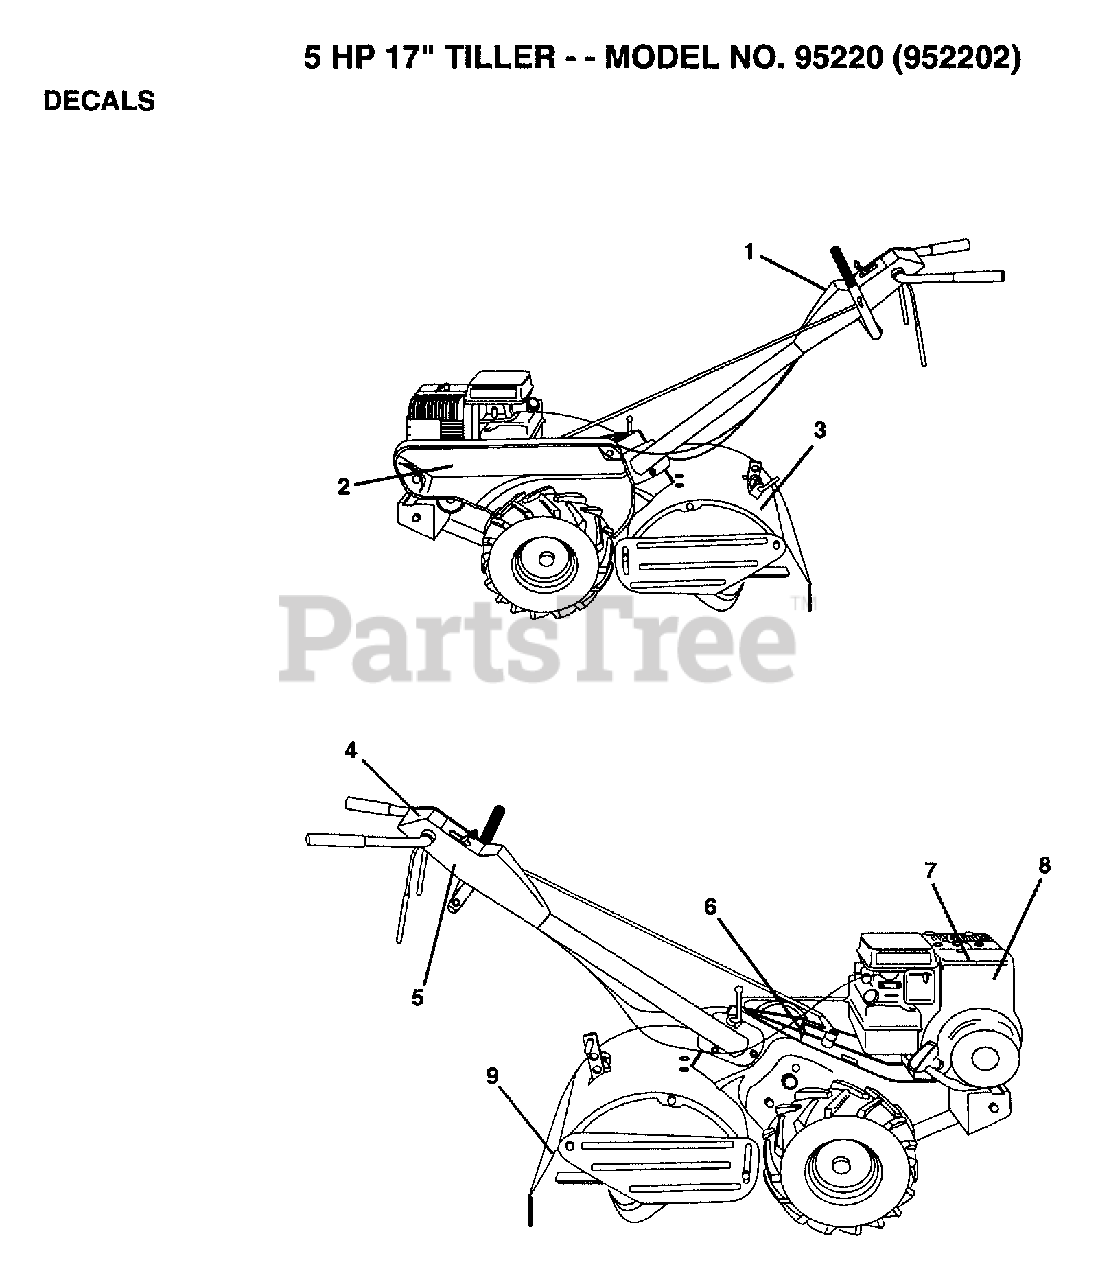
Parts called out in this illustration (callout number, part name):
1	DECAL.PANEL.CONTR
2	DECAL.GUARD.BELT
3	DECAL SHIELD TINE
4	DECAL.INSTRUCTION
5	DECAL TI
6	DECAL CRT
9	DECAL TI
